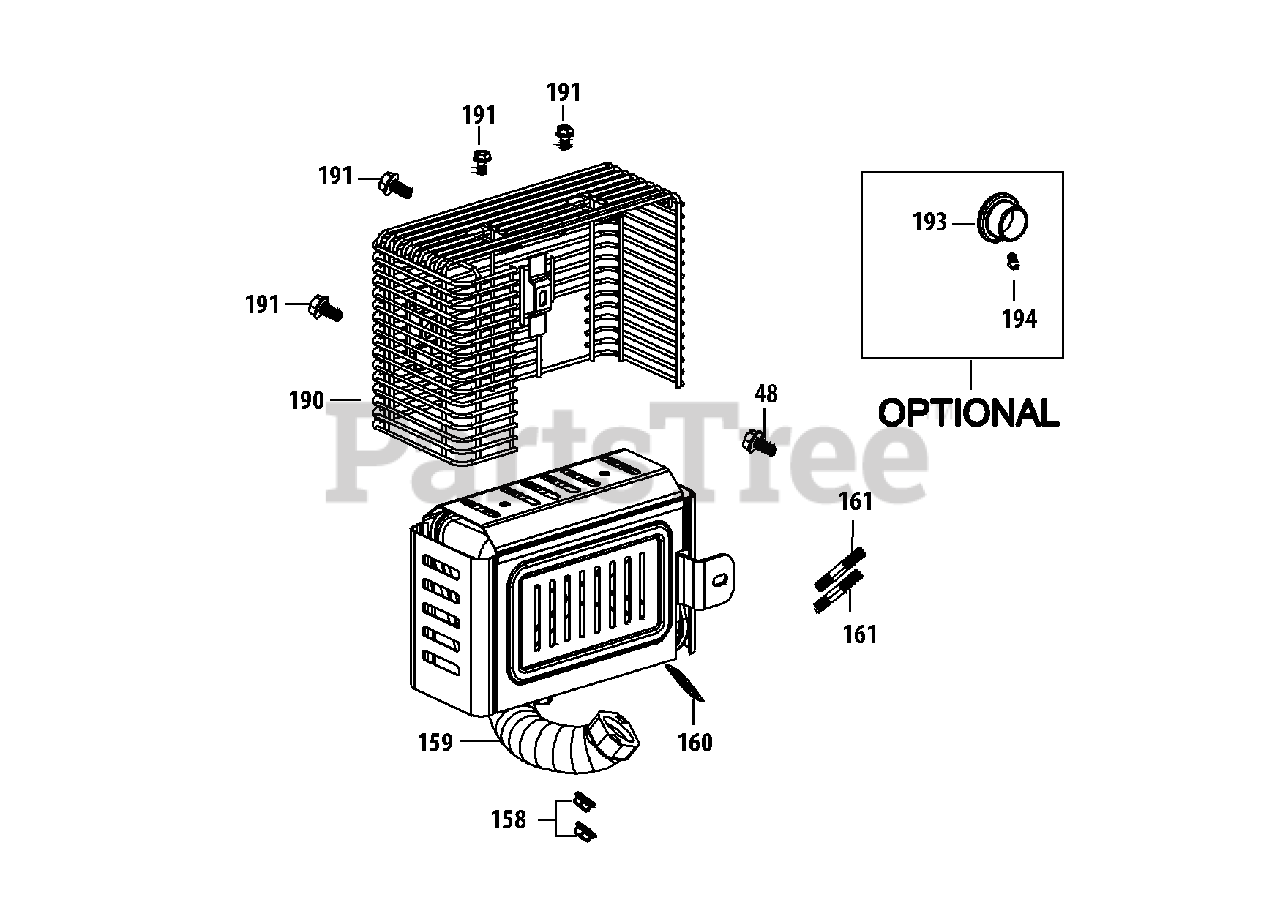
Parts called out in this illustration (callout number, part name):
48	Bolt M6×14
159	Muffler Assembly
160	Exhaust Pipe Gasket
161	Muff Stud M8×47
161	Muffler Stud Assembly
190	Wire Mesh Shield
191	Bolt M6×12
193	Spark Arrestor
194	Spark Arrestor Screw
